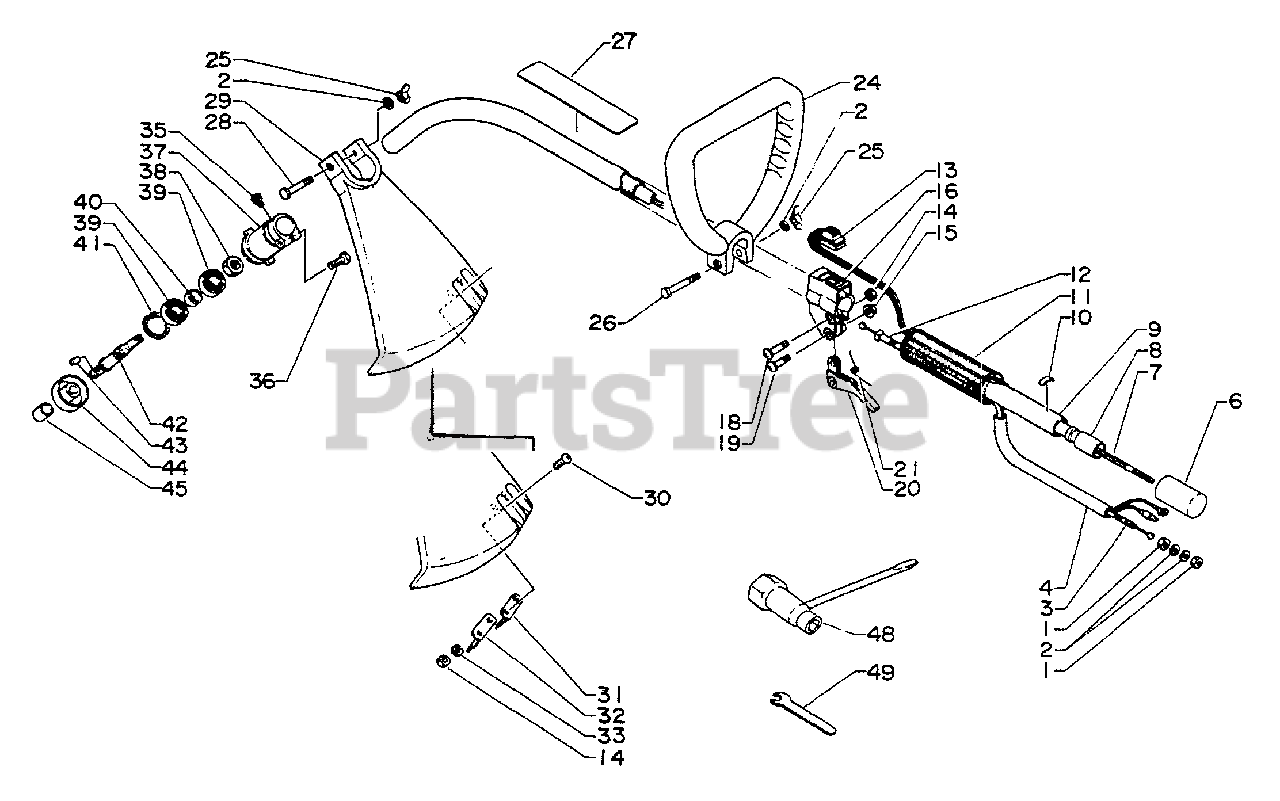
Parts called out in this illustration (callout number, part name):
2	WASHER - 6
3	CABLE, THROTTLE
4	TUBE
6	Cap, housing
7	DRIVESHAFT - FLEXIBLE
8	BUSHING
9	PIPE, MAIN
10	LABEL - ALIGNMENT
11	GRIP, HANDLE
12	GUIDE, CABLE
13	IGNITION SWITCH ASSY
15	LOCKNUT - 5
16	BRACKET, THROTTLE
18	SCREW - 5X28
19	SCREW - 5X30
20	TRIGGER, THROTTLE
21	SPRING, TRIGGER
24	HANDLE ASSY
25	WINGNUT - 6
26	BOLT - 6X40
27	LABEL - CAUTION
28	BOLT - 6X50
29	SHIELD, DEBRIS - PLASTIC
30	SCREW - 5X14
31	KNIFE, TRIMMER LINE
33	LOCKWASHER - 5
35	SCREW - 4X10
36	BOLT - 5X25
37	CASE, GEAR
38	NUT - 12 -- LEFT HAND
39	BEARING, BALL - 6001 DDU
41	RING, RETAINING - 28
42	GEAR - SHAFT
43	PIN - 3X6
44	ADAPTOR, BLADE - UPPER
45	CAP, DRIVESHAFT
48	T-WRENCH - 8X19mm
49	SPANNER - 10mm
